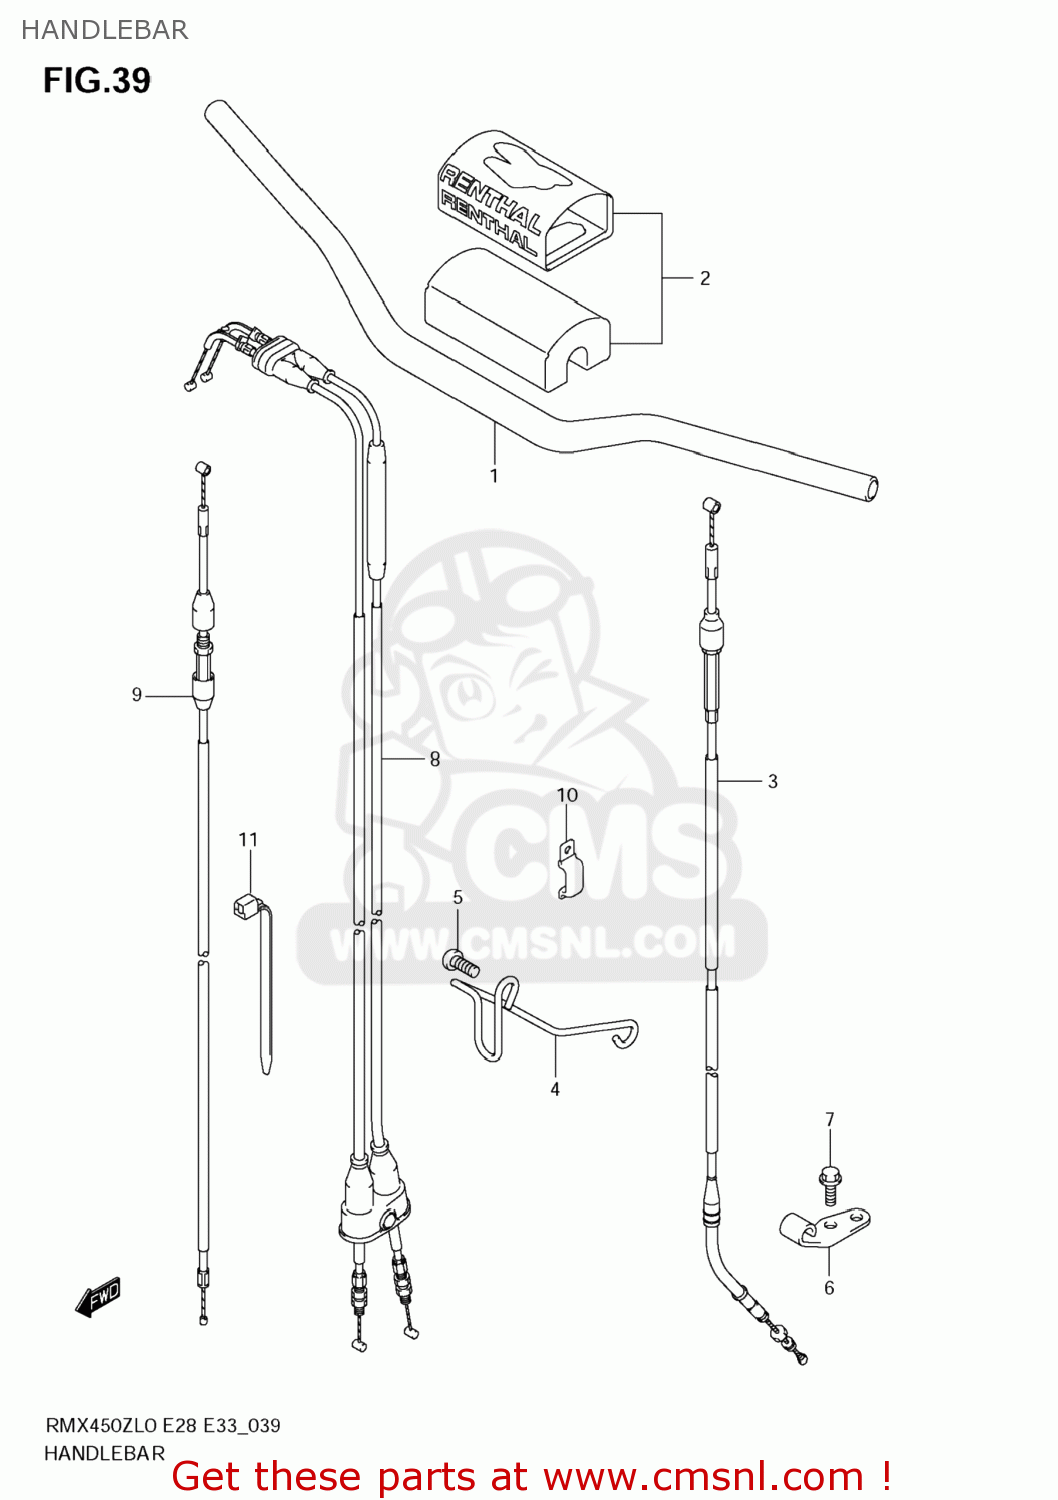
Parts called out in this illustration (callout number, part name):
1	HANDLEBAR
2	PAD SET,HANDLEBAR (NAS)
3	CABLE ASSY,CLUTCH
4	GUIDE,CABLE
5	SCREW
6	STOPPER,CLUTCH CABLE
7	BOLT
8	CABLE SET,THROTTLE
9	CABLE ASSY,HOT STARTER
10	CLAMP
11	CLAMP(L:95)
